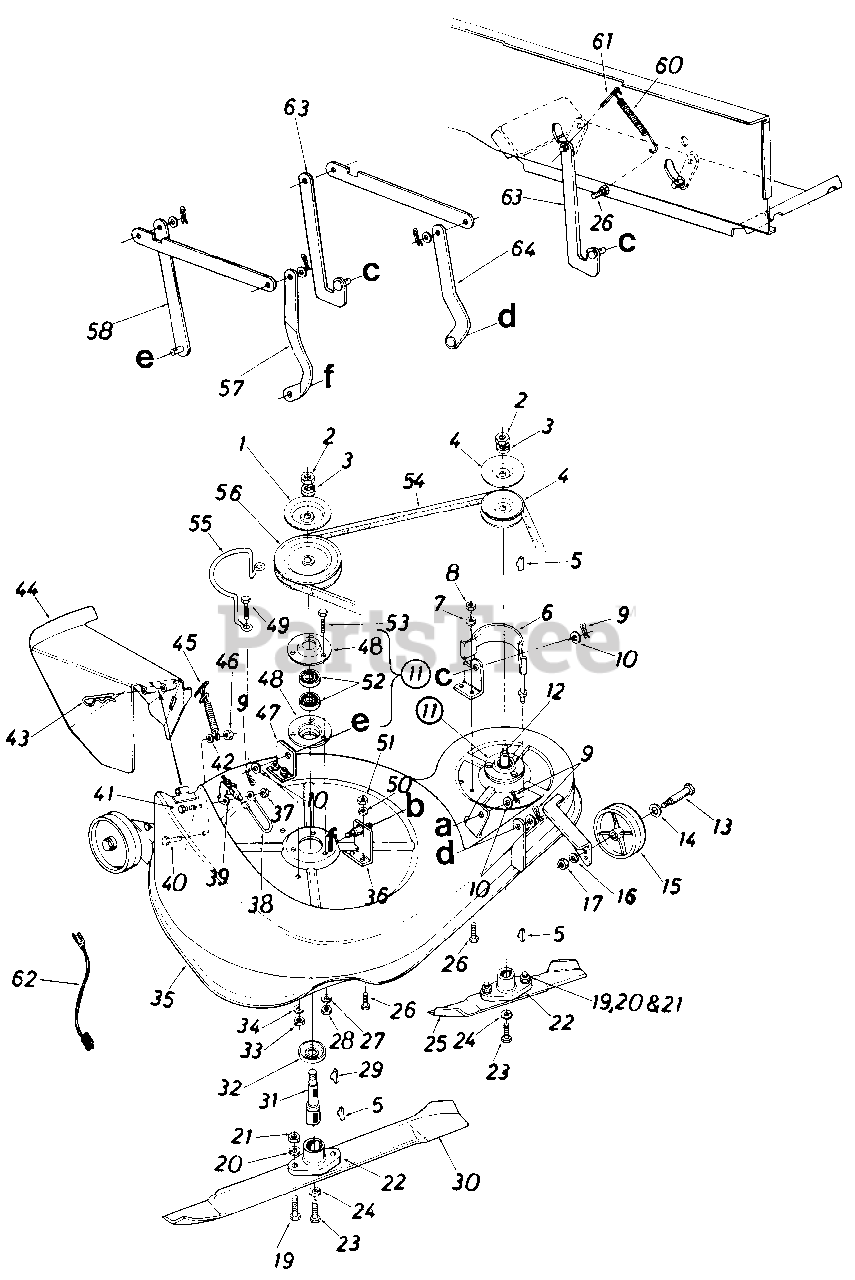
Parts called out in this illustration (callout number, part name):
1	Brake Disc
2	Hex Jam Nut 5/16-18 Thd.
3	Bell-Wash. .630" I.D. x 1.25" O.D.
4	Pulley Ass'y. 3.5" O.D. x 5/8
5	#6 Hi-Pro Key 5/32" x 5/8" Dia.
6	Belt Guard Ass'y.-L.H.
7	L-Wash. 5/16" I.D.
8	Hex Nut 5/16-18 Thd.
9	Internal Cotter Pin 1/2" Dia.
10	Fl-Wash. .531" I.D. x .93" O.D.
11	Blade Spindle Ass'y.
12	Blade Spindle
13	Shld. Bolt .498" Dia. x 1.635
14	Bell-Wash. .400" I.D. x .88" O.D.
15	Deck Wheel 5.0" x 1.38"
16	L-Wash. 5/16" I.D.
17	Hex ut 3/8-16 Thd .
19	Hex Bolt 5/16-24 x 1.00" Lg. (Grade 5)
20	L-Wash. 5/16" I.D.
21	Hex Nut 5/16-24 Thd.*
22	Blade Adapter
23	Hex Bolt 3/8-24 x 1.50" Lg. (Grade 5)
24	L-Wash. 3/8" I.D. H.D.
25	13" Blade
26	Hex Bolt 5/16-18 x .75" Lg.
27	L-Wash. 5/16" I.D.
28	Hex Nut 5/16-18 Thd.*
29	#6 Hi-Pro Key 5/32" x 518" Dia.
30	24" Blade
31	Blade Spindle
32	Bearing Shield
33	Hex Nut 5/16-18 Thd.
34	L-Wash. 5/16" I.D.*
35	36" Deck Assy.
36	Deck Hanger Brkt.-R.H. Front
37	Hex Nut 1/4-20 Thd
38	Ground Wire
39	Safety Switch
40	Truss Mach. Scr. 1/4-20 x .50" Lg.
41	Hex Bolt 1/4-20 x .62" Lg.
42	Fl-Wash. .281" I.D. x .50" O.D.
43	Internal Cotter Pin
44	Chute Deflector Ass'y.
45	Spring Latch Ass'y.
46	Hex Nut 1/4-20 Thd.
47	Deck Hanger Brkt.-R.H. Rear
48	Brg. Housing 1.85" I.D.
49	Hex Bolt 5/16-18 x .75" Lg.
50	L-Wash. 5/16" I.D.
51	Hex Nut 5/16-18 Thd.*
52	Ball Brg. .787" I.D. x 1.85" O.D.
53	Hex Bolt 5/16-18 x .75" Lg.
54	"V"-Belt 1/2" x 71" Lg.
55	Belt Guard
56	Pulley 6.0" O.D. x 5/8"
57	Link Deck Hanger-Front-R.H
58	Link Deck Hanger Ass'y.-Rear R.H.
60	Ext. Spring
61	Cotter Pin 1/8" Dia. x 1.25" Lg.
62	Wire Lead
63	Link Deck Hanger Ass'y.-Rear L.H
64	Link Deck Hanger Ass'y.-Front L.H
